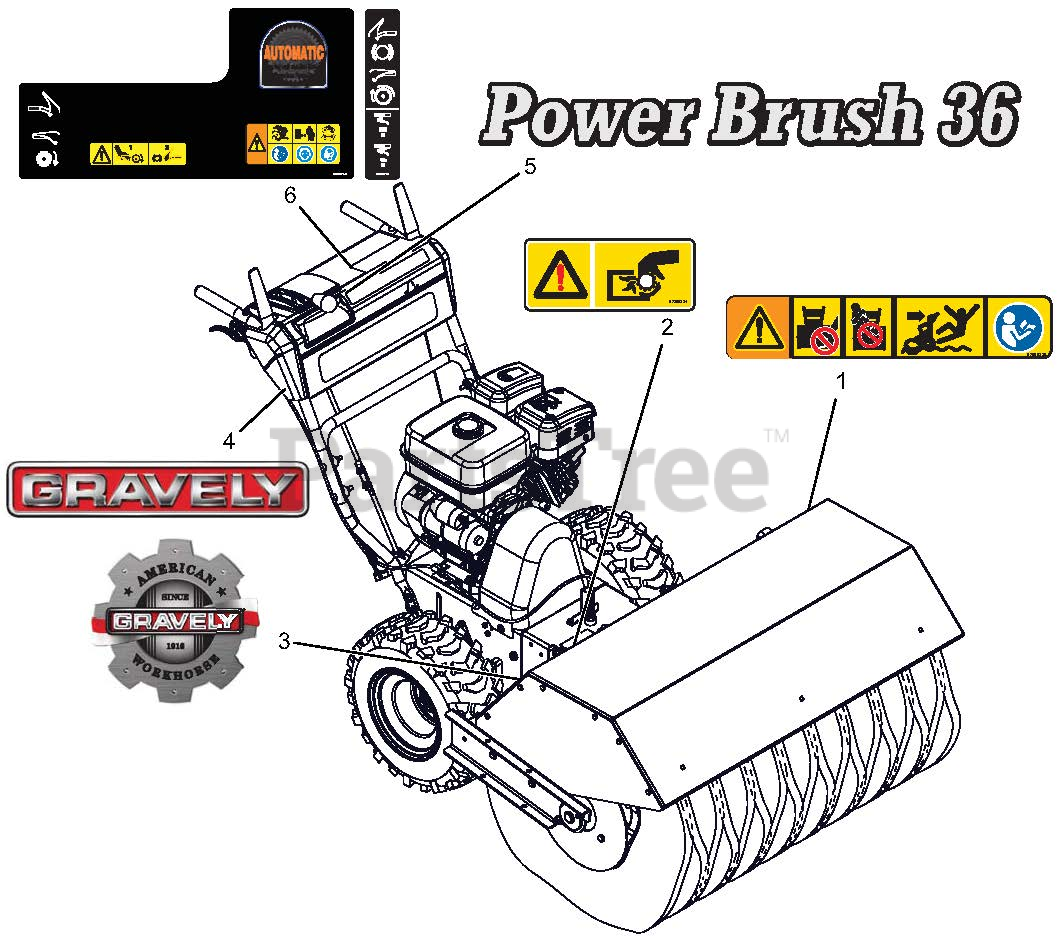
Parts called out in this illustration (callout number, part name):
1	DECAL, DANGER - POWER BURSH CE
2	DECAL, DANGER - PTO WARNING
3	DECAL, GRAVELY HERITAGE-LARGE
4	DECAL, 15" GRAVELY LOGO REV
5	DECAL, POWER BRUSH - 36" GRAVELY
6	DECAL, CONTROL - LARGE BRUSH
